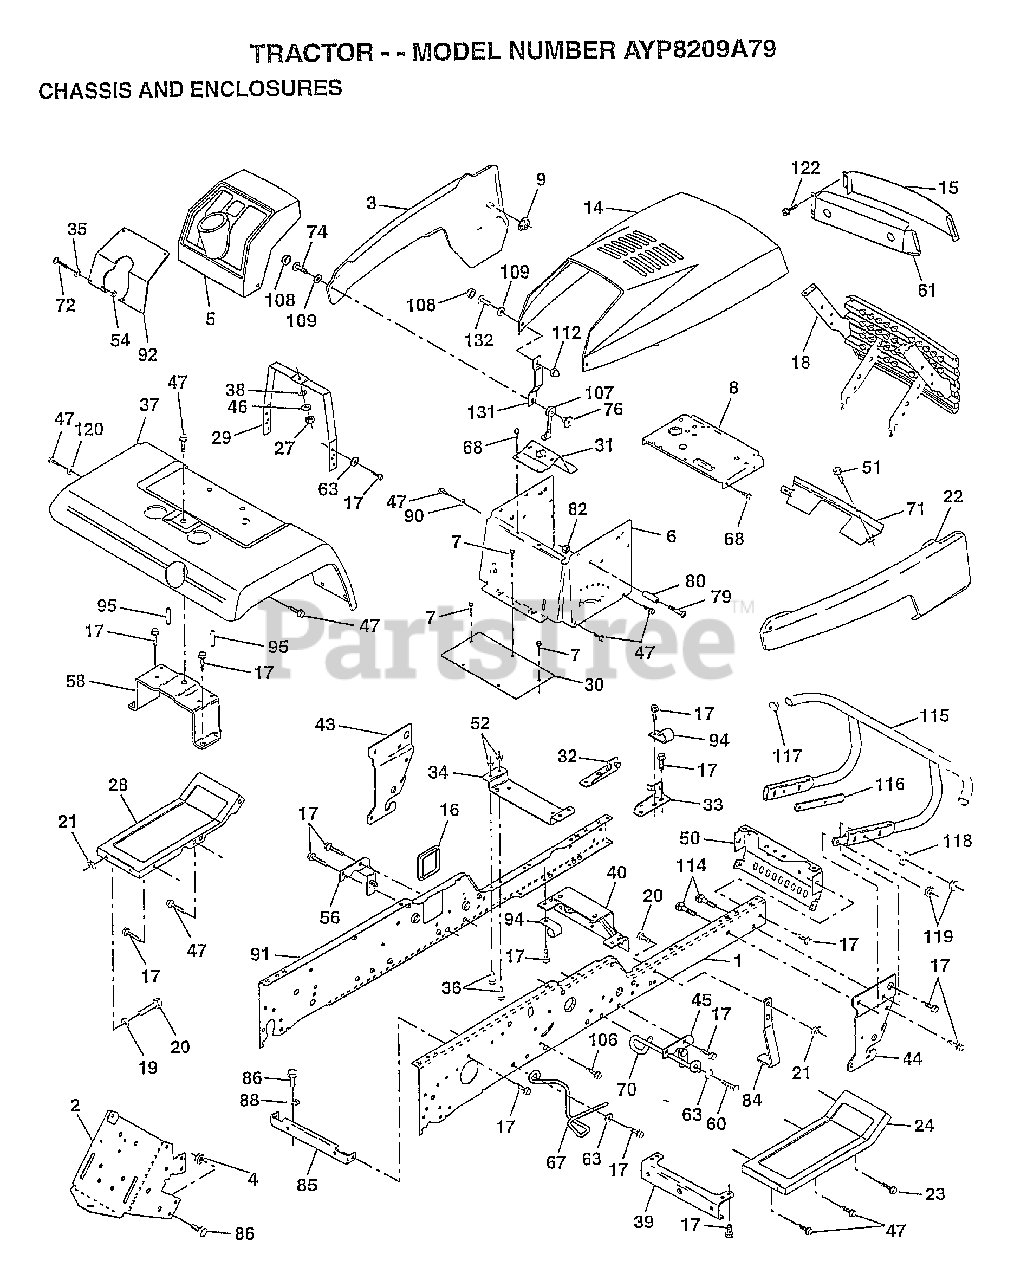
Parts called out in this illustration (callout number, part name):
1	"RAIL,FRAME RH"
2	DRAWBAR GT
3	"PANEL,ASM SIDE LH"
4	NUT GTV
5	DASHBOARD BLACK
6	DASH LOWER
7	SCREW
8	SUPPORT.DASH.BTRY
9	PAL NUT LT
14	"HOOD ASM.,PNT"
15	LENS.BAR.CLEAR
16	COVER ACCESS
17	SCREW
19	WASHER
20	BOLT
22	PANEL ASM.SIDE RH
23	SCREW GTV
24	FOOTREST.RH.LT/GT
28	FOOTREST.LT.LT/GT
29	DASH.SUPT.YP/HUSQ
30	SADDLE.SCR.6SP
31	BRAKET.SUPT.STEER
32	BRACKET ASM FRAME
33	BRACKET ASM FRAME
34	BRACKET.ENG.SUPT.
35	WASHER
36	BOLT
37	"FENDER,RH"
38	LOCKWASHER
39	BRACKET.AXLE.FRT.
40	"BRKT SUPPORT,AXLE"
43	BRACKET.SUS.FT.LH
44	BRACKET.SUS.FT.RH
45	BRACKET.SUSP.RH.
46	WASHER PM
47	SCREW LT
50	"BRKT CHASSIS,FRNT"
51	SCREW CRT
56	BRACKET.SUSP.LH.
58	BRKT.ASM.FENDER
60	SCREW
61	BEZEL.ASM.
63	WASHER
67	"GUIDE BELT, T/A"
68	SCREW LT
70	GUIDE.BELT.MID.SP
72	SCREW
74	SCREW
76	WELDNUT
79	SCREW
80	SPACER LT
84	STOP.OVER.CENTER
85	BRACKET.SUPT.TRAN
86	BOLT
88	LOCKWASHER
90	LOCKWASHER
91	"RAIL FRAME,LH"
92	"PLATE DASH,SLKSCR"
94	CLIP GTV
95	NUT-PUSH YT
107	HOOD LATCH T
108	SNAP CAP LT
109	WASHER LT
112	ACORN NUT RB
114	BOLT.3/8-14X1.25
115	BUMPER.ASM
116	BRACKET.EXT.BUMP.
117	PLUG.PLASTIC
118	WASHER
120	WASHER HYT
131	BKT.SPT.HOOD/PANL
132	SCREW.10-24X3/8.
